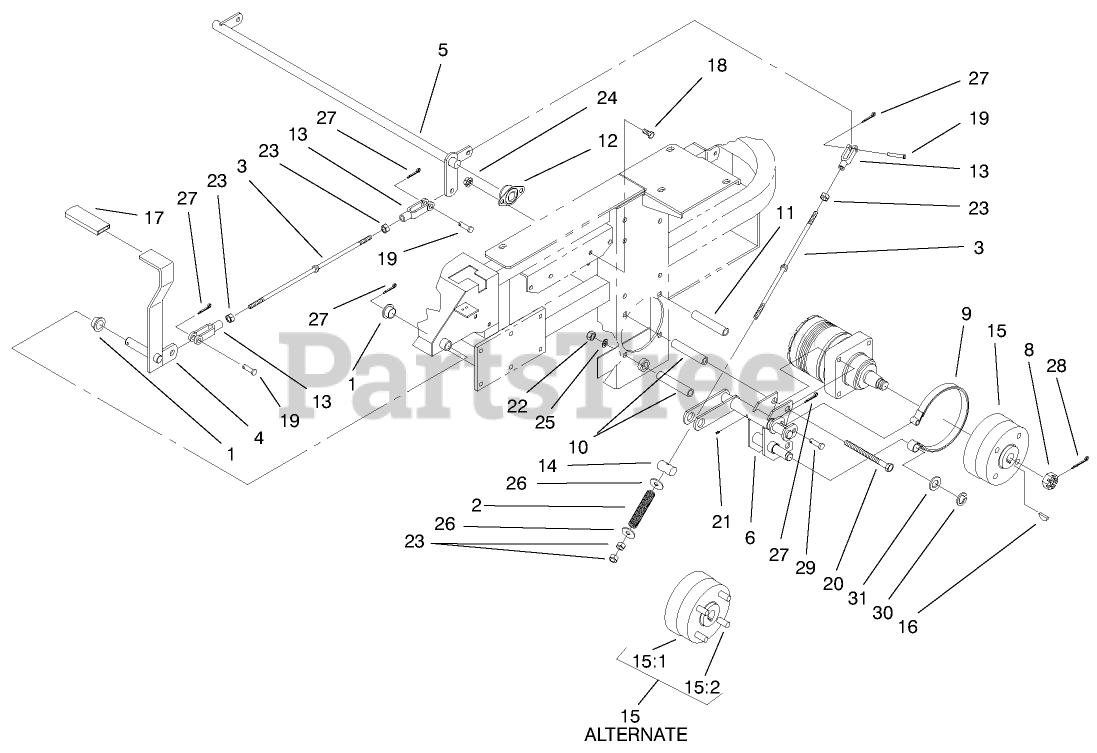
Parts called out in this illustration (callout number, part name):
1	Bearing
2	Spring-Brake
3	Rod-Brake
4	Lever-Brake
5	Shaft-Brake
6	Bracket-Brake LH
8	Nut
9	Band-Brake
10	Spacer
11	Spacer
12	Bearing-Side Flange
13	Yoke-Brake Linkage
14	Pin-Trunion
15	Hub-Wheel
15	Hub And Drum ASM
15:2	Stud-Wheel
16	Key-Woodruff
17	Grip-Brake Lever
18	SCREW-HH
19	Pin-Clevis
20	SCREW-HH
21	Fitting-Grease
22	NUT-HH
23	NUT-HEX
24	NUT-HHF, WHIZ
25	WASHER-LOCK
26	WASHER-FLAT
27	PIN-COTTER
28	Pin-Cotter
29	Pin-Clevis
30	Ring-Retaining
31	Washer
